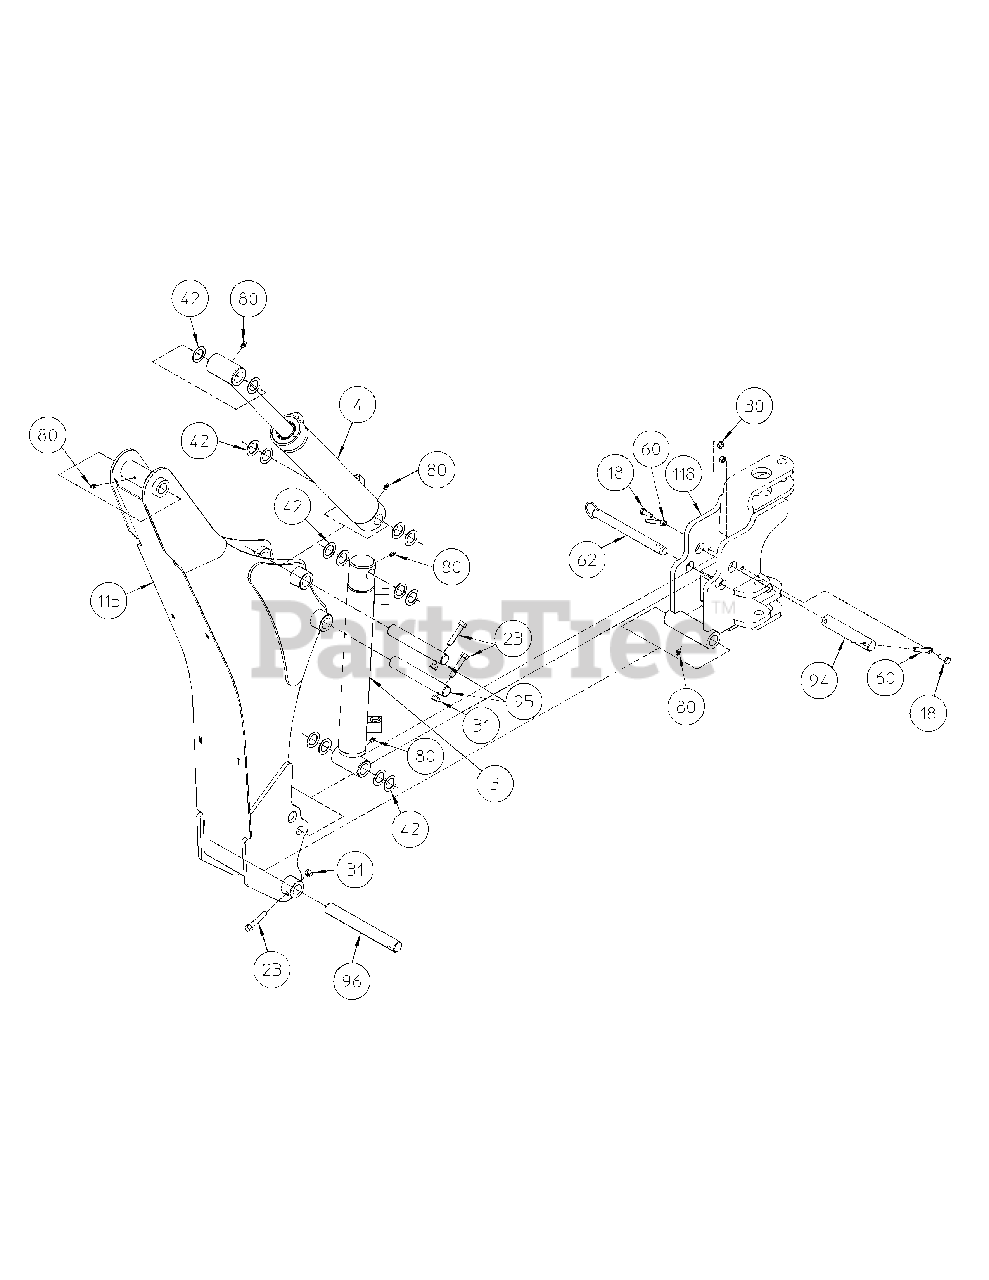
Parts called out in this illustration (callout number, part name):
3	HYDRAULIC CYLINDER, BOOM
4	HYDRAULIC CYLINDER, DIPPER
18	HEX HEAD 5/16-24 X 1.000 GR 5
23	HEX HEAD CAP SCREW, 3/8-24 X 2.0 GR 8 SAE
30	NUT, HEX 5/16-24 LOCK
31	NUT, HEX 3/8-24 LOCK
42	MACHINE BUSHING, 1 X 1-1/2 X 18GA
60	RETAINER PIN-SMALL
62	FASPIN, 3/4 DIA X 7-1/4
80	GREASE FITTING, 1/4-28, STRT
94	PIN, 1 DIA X 5-11/16
95	PIN, 1 DIA X 6-9/16
96	PIN, 1 DIA X 8-1/2
115	BOOM WELDMENT
118	SWING FRAME WELDMENT
